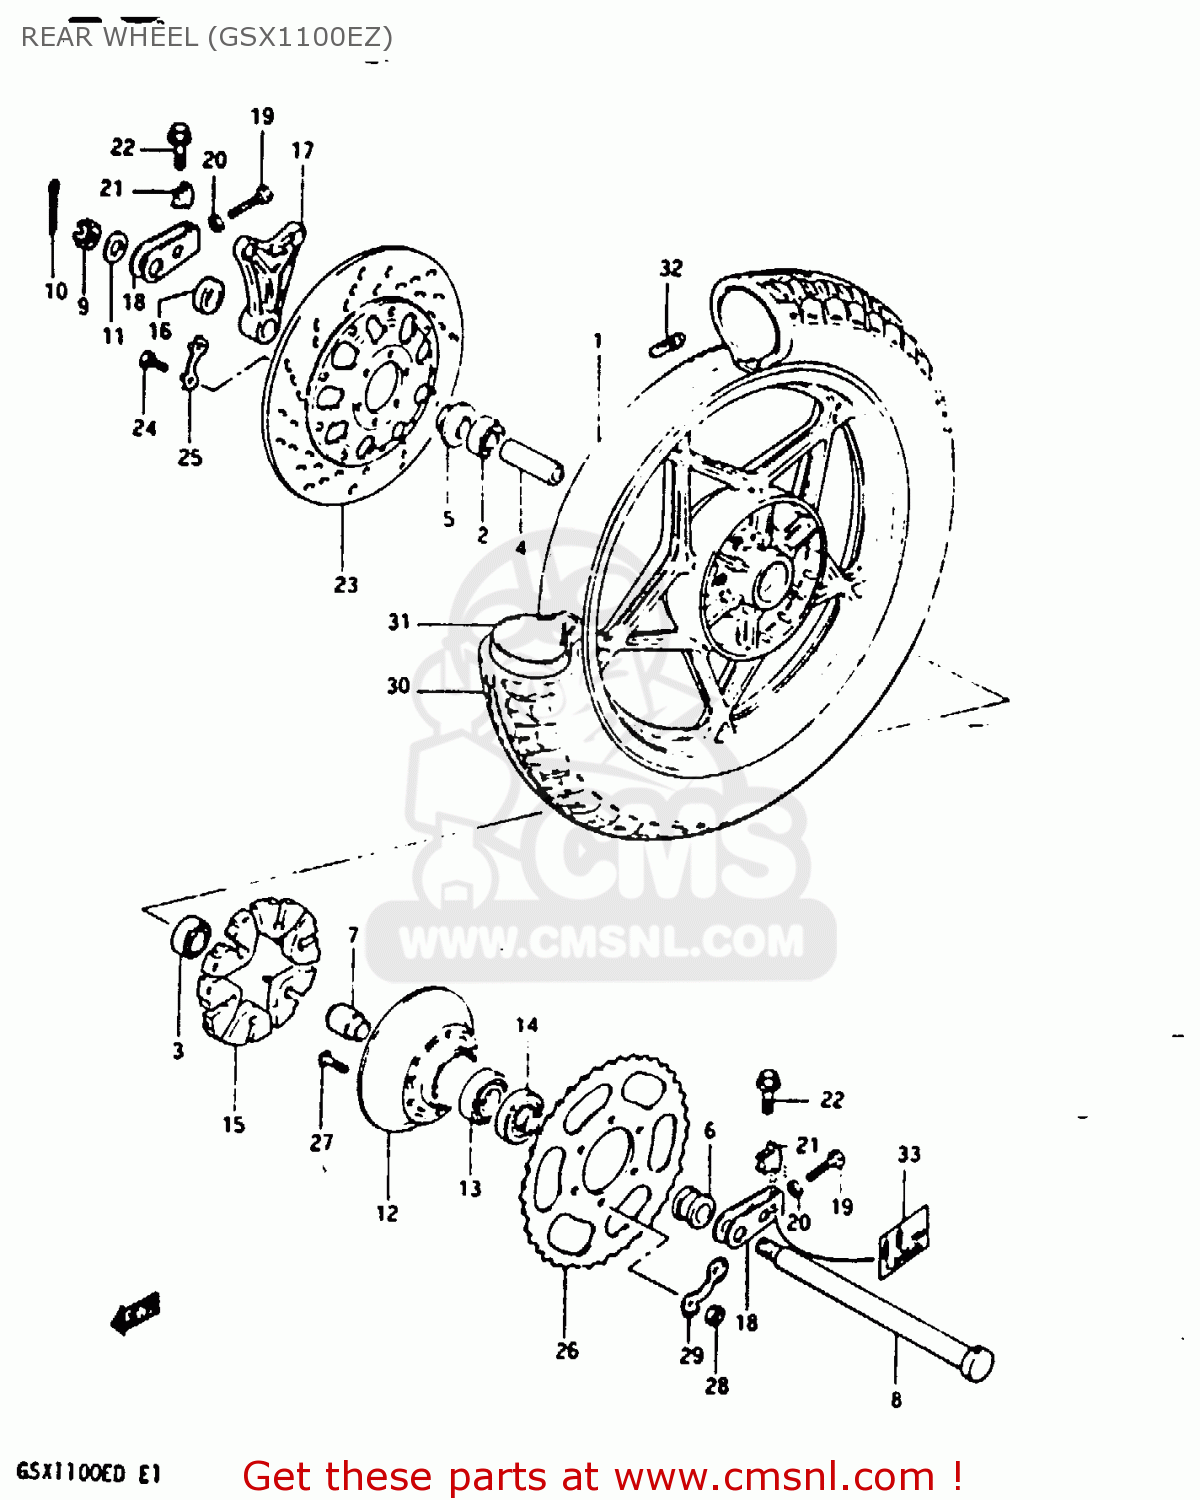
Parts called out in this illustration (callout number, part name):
1	CASTING WHEEL,REAR 2.50-
2	BEARING WHEEL REAR(20X47X14)
3	BEARING, LH
4	SPACER(20.5X28X88)
5	SPACER,REAR AXLE
6	SPACER(20X33X28.3)
7	SPACER,REAR HUB BEARING
8	AXLE,REAR
9	NUT 18MM
10	PIN,COTTER
11	WASHER(19X34X4)
12	DRUM,REAR SPROCKET MOUNT
13	BEARING
14	SEAL,OIL(33X62X7)
15	ABSORBER,REAR HUB SHOCK
16	SPACER(20X38X12)
17	BRACKET,RR,CALIPER
18	ADJUSTER,CHAIN
19	BOLT 8X50
20	NUT
21	SUPPORTER,CHAIN ADJUST
22	BOLT
23	DISC,RR BRAKE
24	BOLT(8X30)
25	WASHER
26	SPROCKET,REAR
27	BOLT
28	NUT
29	WASHER
30	TIRE
31	TUBE ASSEMBLY,WHEEL,INNER
32	BALANCER,WHEEL
33	LABEL,CHAIN WEAR INDICATOR
